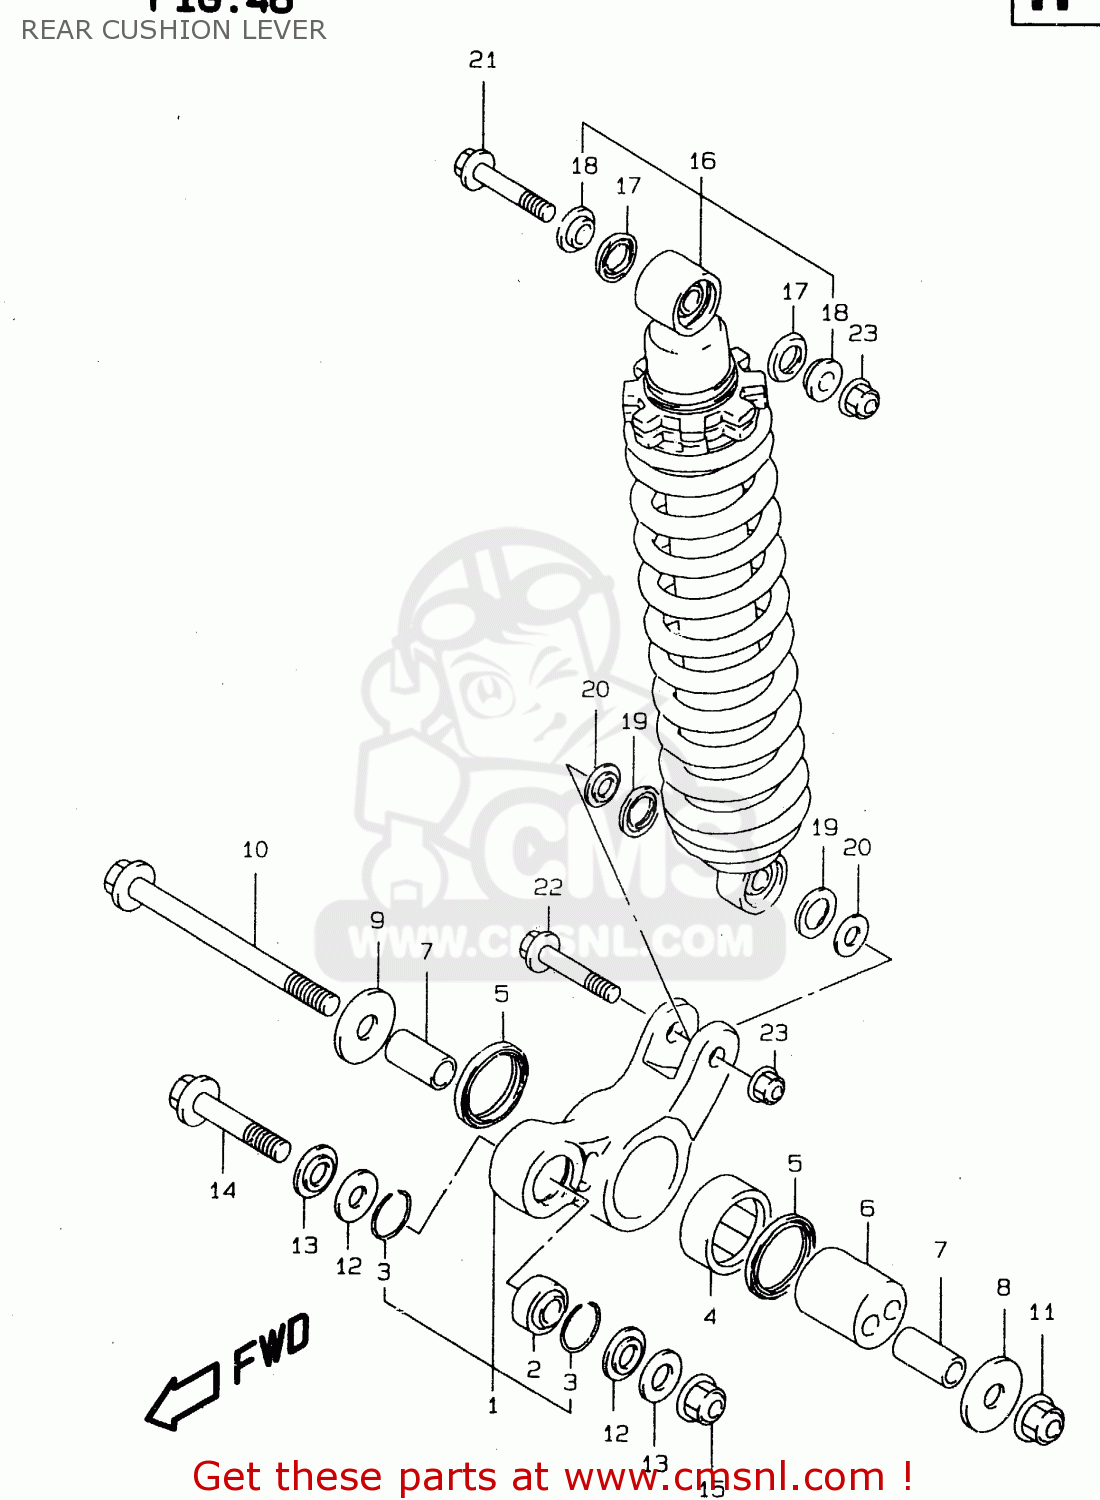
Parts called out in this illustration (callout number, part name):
1	LEVER SET,RR CUSHION
2	BEARING(12X26X16)
3	RING,BEARING STOPPER
4	BEARING(37X47X20)
5	SEAL,DUST
6	SPACER,RR SUSPENSION ECCENTRIC
7	SPACER,CUSHION LEVER SHAFT
8	WASHER,RR CUSH LVR CTR,L
9	WASHER,RR CUSH LVR CTR,R
10	SHAFT,RR CUSHION LEVER CTR
11	NUT 12MM
12	SEAL,RR CUSHION ROD DUST
13	SPACER,RR CUSHION ROD
14	BOLT,CUSHION LEVER FR
15	NUT 12MM
16	ABSORBER ASSEMBLY,REAR SHOCK
17	DUST SEAL
18	SPACER
19	DUST SEAL,RR SHOCK
20	COLLAR
21	BOLT,REAR SHOCK ABSORBER
22	BOLT(10X48)
23	NUT
